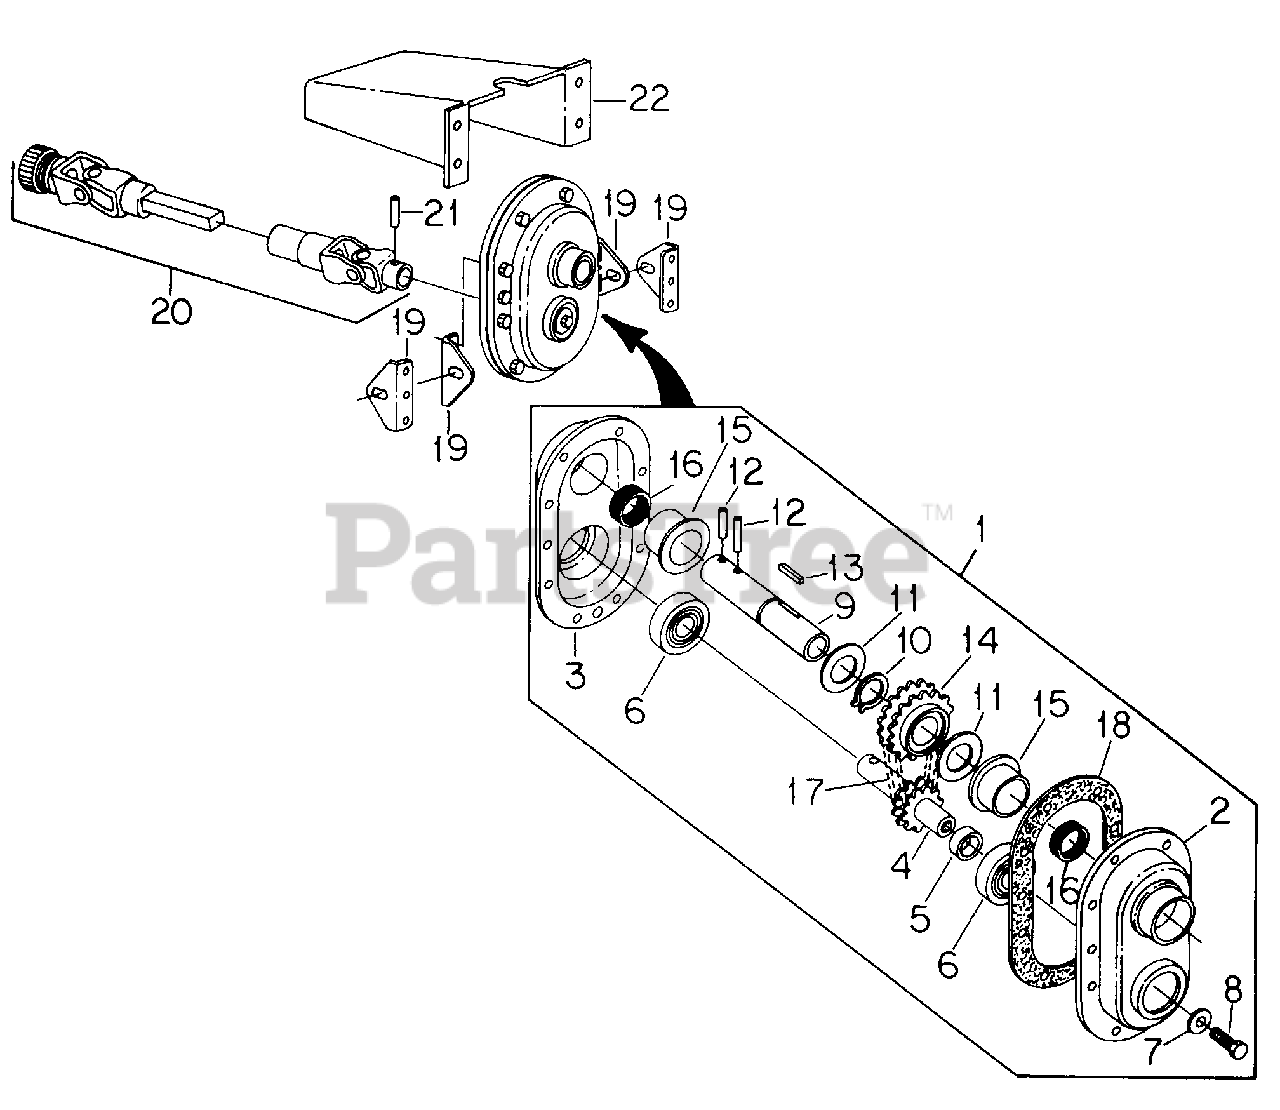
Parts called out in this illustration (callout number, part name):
1	Drive Assy, Chain
2	Housing, Chain Drive Front
3	Housing, Chain Drive Rear
4	Shaft, Sprocket
5	Spacer, 1.0 X 1.18 X .44
6	Bearing, Ball
7	Washer, .40 X 1.25 X .157 Belleville
8	Bolt, 3/8 X 1 Phc P/T Type 8
9	Sleeve, Sprocket
10	Ring, 1.156 Ext Ret
11	Washer, 1.25 X 2.0 X .060 Flat
12	Pin, 5/16 X 1-3/4 Hvy Pln Cld Spr
13	Key, 1/4 X 1 Sq. Parallel
14	Sprocket, Driven
15	Bearing, Flange
17	Chain, 40-2 1/2 Pitch X 25 Links
18	Gasket, Housing
19	Bracket, Chain Drive Mounting
20	Shaft, U-Joint Drive -PTO to chain drive
21	Pin, 5/16 X 2-1/2 Hvy Pln Cld Spr
22	Cover, Drive Shaft
